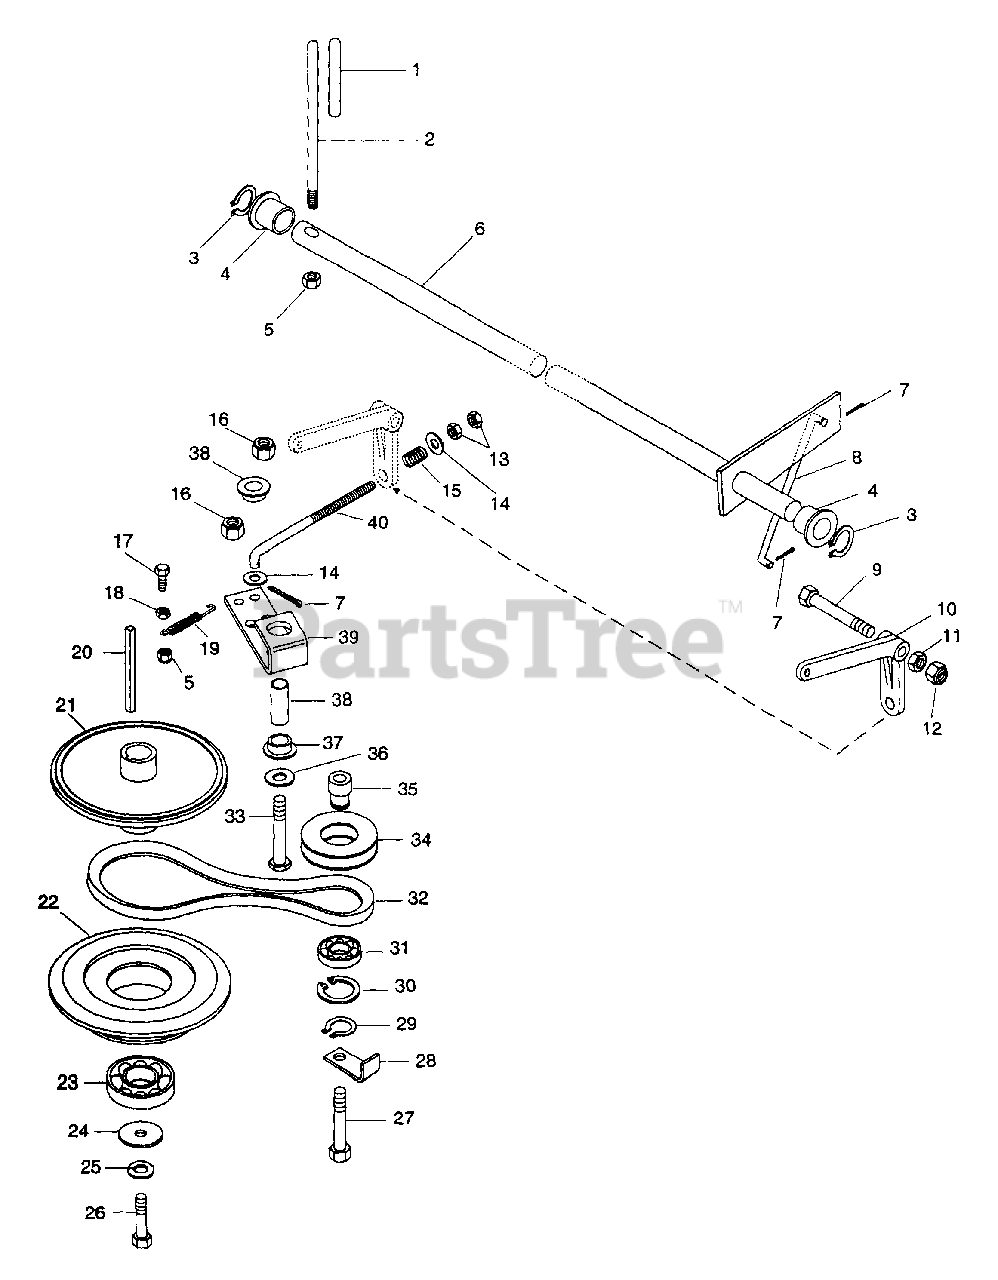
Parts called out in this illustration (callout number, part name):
1	Grip, Hand Clutch Lever
2	Lever, PTO Actuating
3	Ring, Retaining-External .625 x .050
4	Bushing, Flange .630 x 1.00 x .625 Nylon
5	Nut, Lock Nylon .312 - 18
6	Weldment, Pto Actuating Shaft
7	Pin, Cotter .09 x .75
8	Rod, Pto Actuating
9	Bolt, Hex .50-13 x 2.25 Gr. 5
10	Lever, Pro Clutch
11	Nut, Jam .50-13
12	Nut, Lock .50-13 Hex Type N
13	Nut, Hex .375-16
14	Washer, Flat Steel .406 x .812 x .065
15	Spring, Compression .188 x 1.66 x 2.00
16	Nut, Lock Nylon .50-13
17	Bolt, Hex .31-18 x 1.00 Gr. 5
18	Nut, Hex .312-18
19	Spring, Tension .061 x .50 x 3.5 Wld 4
20	Key, Square .25 x 3.635 x .25
21	Hub-Pto Clutch
22	Sheave, Mower Clutch
23	Bearing, Ball 1.57 x 3.15 x .71
24	Washer, Special .469 x 2.00 x .250
25	Washer, Lock .44 Reg.
26	Bolt, Hex .44-20 x 2.50
27	Bolt, Hex .50-13 x 2.50 Gr. 5
28	Guard, Belt
29	Ring, Retaining
30	Ring, Retaining Internal 2.054 x .062
31	Bearing, Ball 1.85 x .787 x .55
32	V-Belt 13.8 x .531
33	Bolt, Hex 1/2-13 x 2.75
34	Sheave, Idler
35	Bushing, Flange .515 x .787 x 1.41
36	Washer, Flat Steel .531 x 1.062 x .095
37	Bushing, Flang .762 x 1.0 x .580 x 1.48 Nylon
38	Bushing, Steel .560 x .745 x 2.04
39	Arm, Idler Pivot
40	Rod, Pto Clutch Actuating
